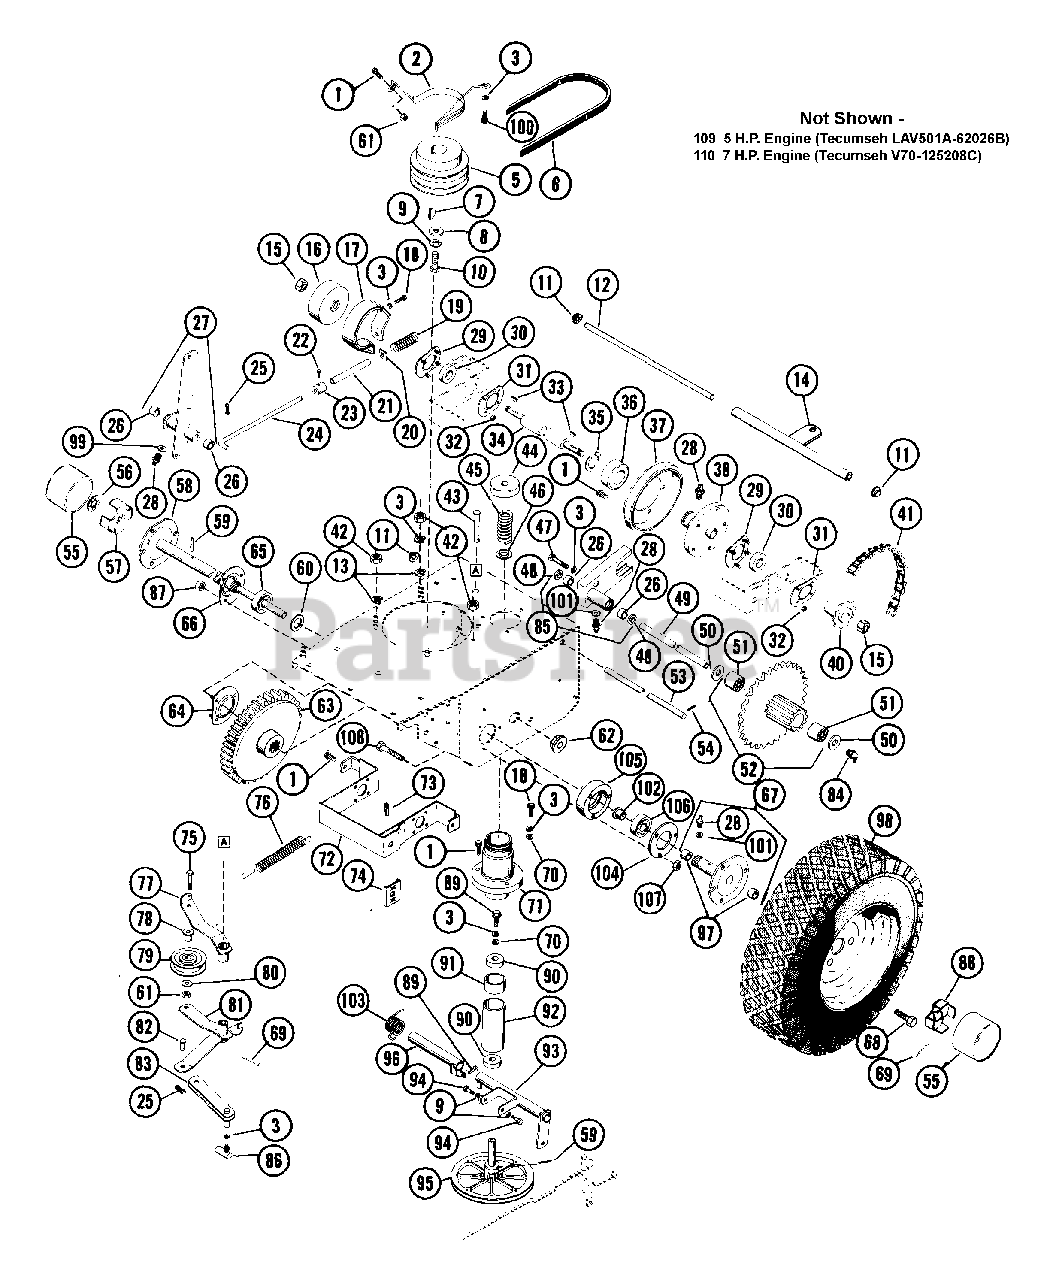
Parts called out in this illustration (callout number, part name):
1	BLT-SERHFWH .31-18X.50 PL
2	REAR BELT FINGER
3	WSHR-LK .312X.097 PL HVY
5	ENGINE SHEAVE
6	V-BELT, SAE 380-RAW EDGE
7	KEY-WDRF .156X.625X.25 SAE 6
8	WSHR-FL-STL .438X1.125X.19
9	WSHR-LK .375X.115 HVY PL
10	BLT-HEX .38-24X1.25 BLKO GR5
11	CAP, .50 ROD YWZC
12	HITCH SHAFT
13	WSHR-LK-INT .313X.030 PL
15	NUT-LK-CTR .50-20 PL
16	BRAKE DRUM
17	BRAKE BAND
18	BLT-HEX .31-18X.50 PL GR2
19	SG-COMP .102X.85X1.031
20	BRAKE BAND WASHER
21	BRAKE SPACER .5 X .4 X 2.63
22	SCR-SET .25-20X.50 SQHCUP HT
23	SET COLLAR
24	BRAKE ROD
25	PIN-COTR .09X.75 PL
26	BSHG-SLV .625X.750X.500 BR
27	CLUTCH BRAKE BELL CRANK
28	SPIN DRIVE ZERK FITTING
29	BEARING FLANGE
30	BRG-BALL .500X1.38X.437
31	BEARING FLANGE
32	NUT-LK DUAL FACE 10-24 PL
33	KEY-WDRF .125X.625X.250 SAE5
34	HEX SHAFT
35	RG-RTNG-EXT 1.250X.050
36	BRG-BALL 1.25X2.18X.63
37	FRICTION DISC
40	9 TOOTH SPROCKET
41	CHAIN
42	NUT-HEX .312-18
43	PIN-CLEVIS .500 X 3.250
45	SG-COMP .148X1.23X2.53 WLD87
46	SPRING RETAINER
47	BLT-HEX .31-24X.50 GR5
48	SEAL .625X.875X.125
49	CARRIER SHAFT
50	WSHR-FL-STL .630X1.005X.062 PL
51	BRG-NEEDLE .625X.812X.50
52	PINION ASSEMBLY
53	DISC FORK ROD
54	PIN-ROLL .188X1.00
55	HUB CAP
56	PUSHNUT
57	SPINDLE CUP
58	R.H. AXLE SHAFT
59	PIN-ROLL .188X1.25
60	WSHR-FL-STL .880X1.380X.062
61	NUT-LK .312-18 GR A PL
62	FLANGE BUSHING
63	DIFFERENTIAL ASSEMBLY
64	BEARING FLANGE
65	BRG-BALL .876 X 1.750 X .50
66	BEARING FLANGE
67	L.H. AXLE ASSEMBLY
68	BLT-WHL .50-20X.75 GR5 PL
69	PIN-COTR .12X1.0 PL
70	WSHR-FL-STL.312X.734X.065PL
71	DRIVE SPRING HOUSING
72	CARRIER
73	PIN-ROLL .188X1.50
74	LOCATING PLATE
75	BLT-HEX .31-18X1.25 PL GR2
76	SG-TENS .063X.44X2.81 WLD 18
77	IDLER ARM
78	SPCR, BRG .315X.50X.688X.281
79	IDLER
80	WSHR-FL-STL .38X.875X.083 PL
81	SHIFT TRANSFER LEVER
82	CLEVIS PIN
83	SHIFT LINK
84	HYDRAULIC DRIVE FITTING
85	SLIDING FORK ASSEMBLY
86	BALL JOINT
87	NUT-LK-FLG .250-20 PL
88	SPINDLE CUP
89	BLT-LK .31-18X.75 GR 5
90	BRG-BALL .625X1.375X.44
91	BEARING SPACER .87 X .63 X 1.2
92	DRIVE SPINDLE HOUSING
93	DISK FORK
94	SCREW PIN
95	DRIVE DISK ASSEMBLY
96	NEUTRAL STOP
97	BSHG-SLV .690X.814X.625
98	TIRE & WHEEL ASSEMBLY
98	WHL 6 IN O.D.
98	TIRE 6 X 4.10/3.50
98	TUBE
98	TURF SAVER TIRE & WHEEL ASSEMB
98	TIRE 13/6.50 X 6
98	WHL
99	WSHR-FL-STL .265X.500X.087 PL
100	BLT-HEX .31-18X1.50 PL GR2
100	BLT-HEX .31-18X1.00 PL GR 2
101	WSHR-LK .250X.047 LT PL
102	BSHG-FLG 1.125X1.25X.75X1.38
103	SG-TORS .086X.75X1.125
104	COVER
105	BEARING FLANGE
106	BRG-BALL 1.25X2.18X.63
107	NUT-LK-CTR .250-20 PL
108	BLT-HEX .25-20X1.25 PL GR5
109	5 H.P. Engine(Tecumseh LAV501A-62026B) orreplacement
110	7 H.P. Engine(Tecumseh V70-125208C) orreplacement
